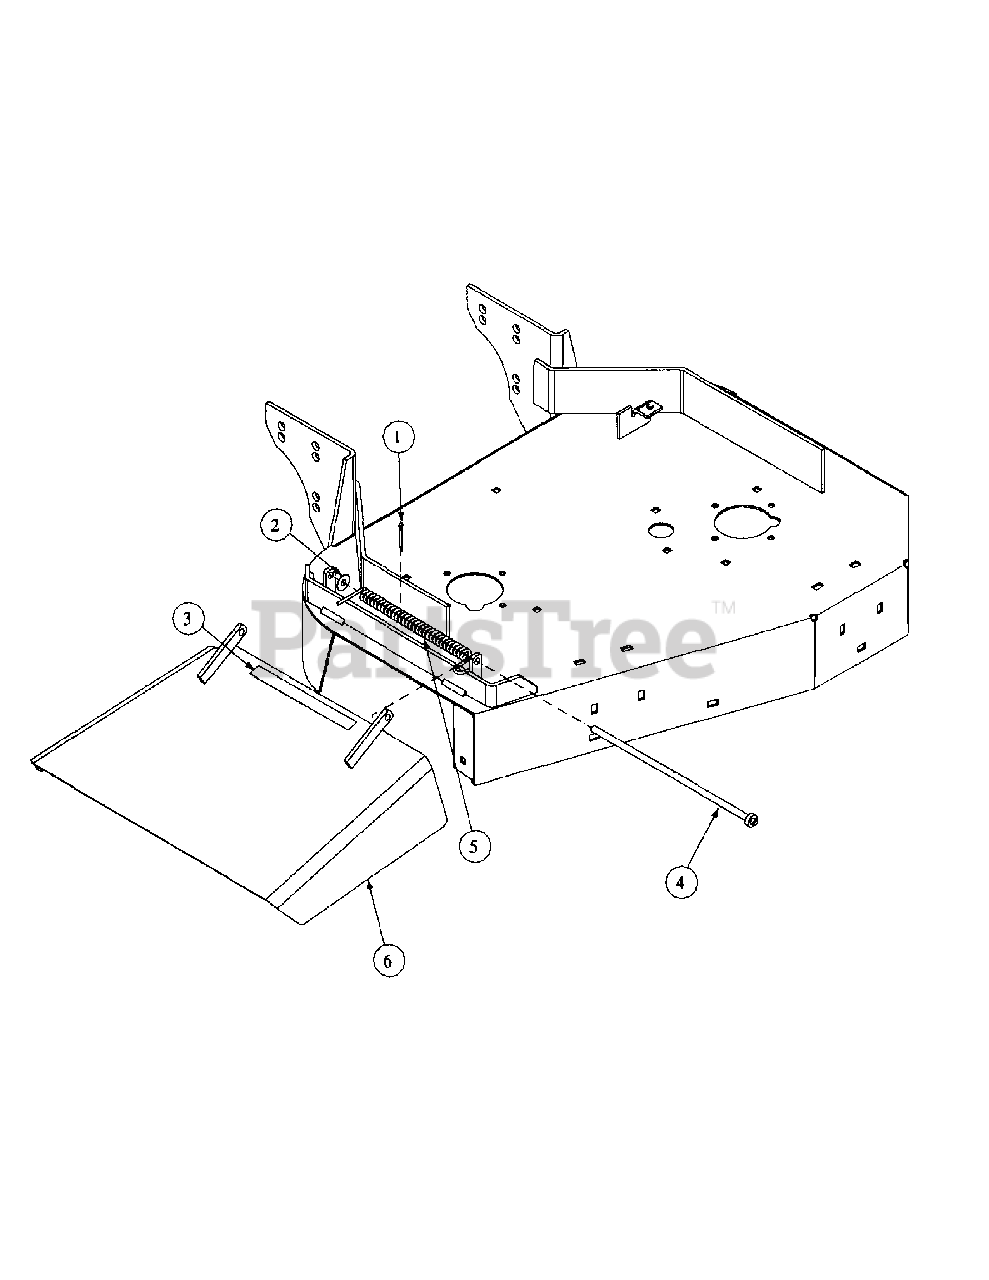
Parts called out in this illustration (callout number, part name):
1	Cotter Pin, 5/32 x 1 1/2 Zinc
2	Flat Washer, 3/8, Zinc
3	Decal, Cut Line
4	Pin, Deflector Assembly, Weldment 1
5	Torsion Spring
6	Chute Assembly Discharge
